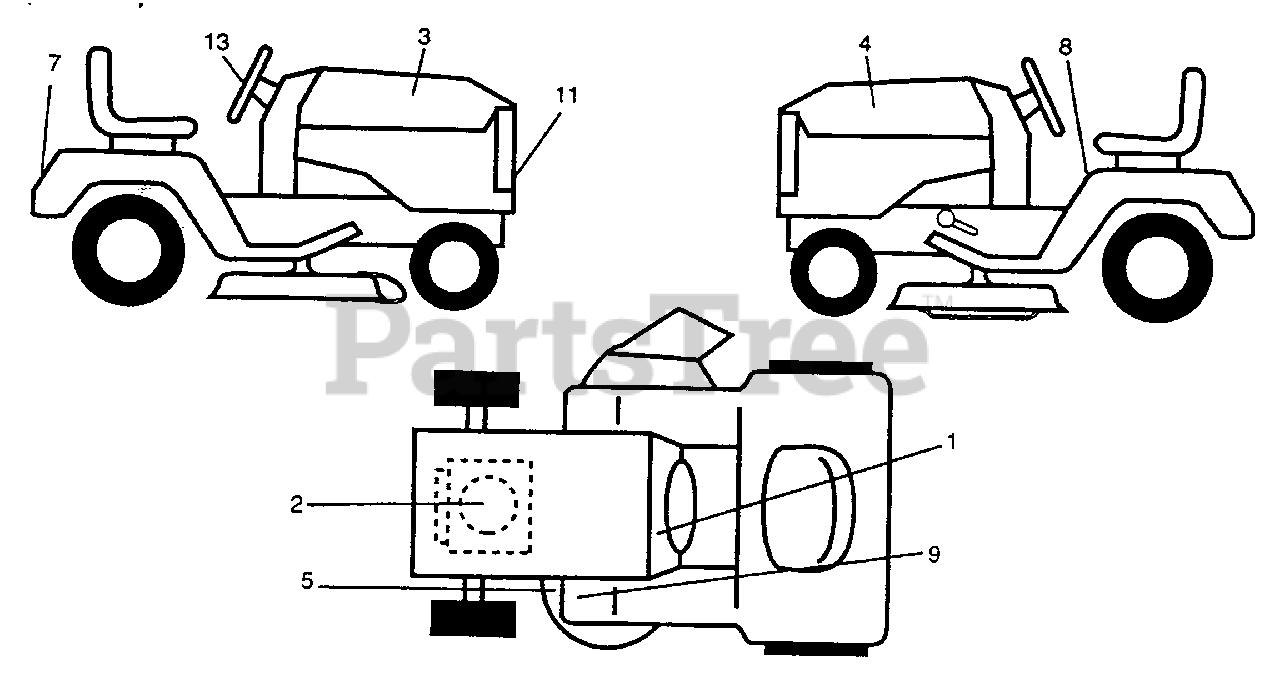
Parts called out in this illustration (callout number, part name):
1	Decal Instruction Dash Eng (AYP part number)
2	Decal HP Engine (AYP part number)
3	Decal Hood RH (AYP part number)
4	Decal Hood LH (AYP part number)
5	Decal V-Belt (AYP part number)
7	Decal Fender (AYP part number)
8	Decal Caution Fender Eng (AYP part number)
9	Decal Clutch/brake Eng (AYP part number)
11	Decal Grille
13	Decal Steering Wheel Cap (AYP part number)
